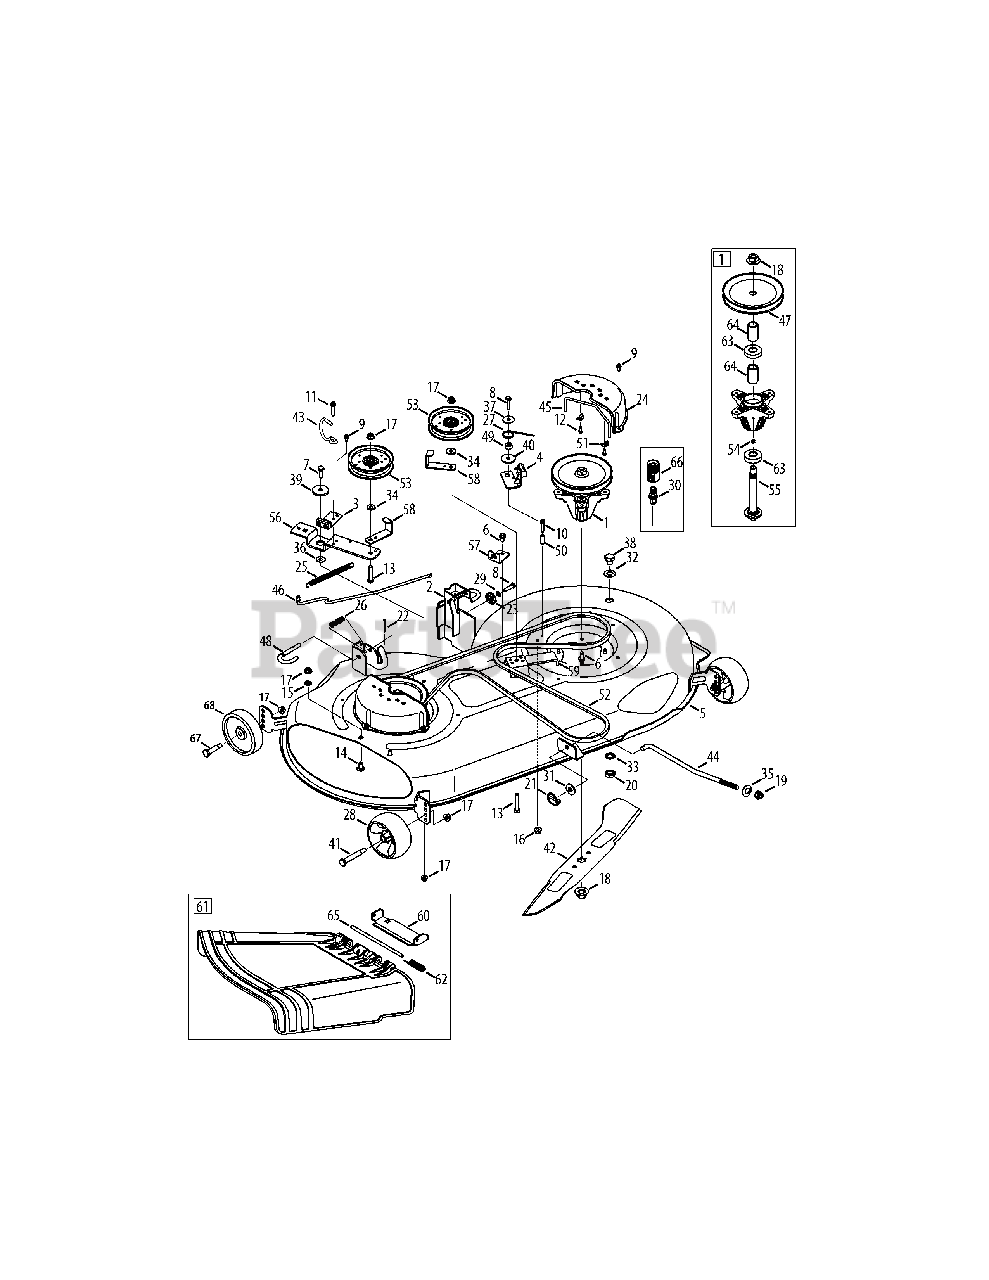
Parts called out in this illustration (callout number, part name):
1	Spindle Ass’y, Pulley, 6.93 Dia
2	Bracket Ass’y, Deck, Hanger LH
3	Brake Ass’y, Deck
4	Brake Ass’y, Deck
5	Deck Ass’y, Offset, 46" 2W
6	Screw, Self-tapping, 5/16-18, .750,
7	Hex Screw, 3/8-16, 1.00
8	Hex Screw, 5/16-18, 1.25
9	Screw, Self-tapping, 1/4-20, 0.500,
10	Screw, Self-tapping, 1/4-20, 1.500,
11	Screw, Self-tapping, 1/4-20, .75,
12	Screw, #10-16:.625
13	Hex Screw, 3/8-16, 2.00
14	Bolt, Carriage, 3/8-16, 0.75
15	Nut, Push, 3/8
16	Nut, Flange Lock, 5/16-18
17	Nut, Flange Lock, 3/8-16
18	Nut, Flange, 5/8-18
19	Nut, Lock, 1/2-13
20	Nut, Hex, M16-1.5
21	Pin, Lynch, .1875
22	Pin, Cotter, 1/8 x 1.25
23	Gear, Deck, Adjustment
24	Belt Cover
25	Spring, Extension, .62 Dia x 6.12
26	Spring, Comp, .535 OD x 1.751
27	Spring, Torsion, .992 I.D x 1.17 O.D
28	Wheel, Deck, 5.0 Dia Ball
29	Washer, Lock, 5/16, Regular Duty
30	Water Nozzle Adaptor
31	Washer, Flat, .531 x 1.25 x .100
32	Washer, Flat, .64 x 1.24 x .06,
33	Washer, Lock, 5/8, Int Tooth
34	Washer, Flat, .385 x .870 x .092
35	Washer, Bell, .63 x 1.25 x .18
36	Washer, Flat, .385 x 1.0 x .030
37	Washer, Flat, .330 x 1.25 x .06,
38	Plug, Bolt, M16 x 1.5
39	Spacer, Shoulder, .8840 x .190
40	Spacer, Shoulder
41	Bolt, Shoulder, .496 x 2.50, 3/8-16
42	Blade
43	Rod, Keeper, Belt
44	Rod, Lift, Deck, Frt, 13.7
45	Rod, Keeper, Belt
46	Rod, Control, Brake
47	Pulley, Deck, 6.93 Dia
48	Rod, Handle, Deck Release
49	Spacer, .315 x .750 x .375
50	Spacer, .260 x .375 x 1.030
51	Clamp, Casing
52	Belt, V-Type
53	Pulley, Idler, 4.25"Dia
54	Fitting, 3/16, Lnc#70, Drive Lube
55	Shift, Spindle, 6.11.
56	Bracket, Idler, Pivot
57	Bracket, Cable, Deck Engage
58	Bracket, Guard, Belt, 4.25 Pulley
59	Bracket, Support, Deck Stationary Idler
60	Bracket, Chute
61	Chute Ass’y, Deflector
62	Torsion Spring, .44 ID x 2.0
63	Ball Bearing, .787 ID x 1.85 OD x .551
64	Spacer, .792 x 1.060 x 1.860
65	Hinge Pin
66	Deck Water Nozzle
67	Bolt, Shoulder, .496 x 1.525, 3/8-16
68	Wheel, Deck 5.0 x 1.38
